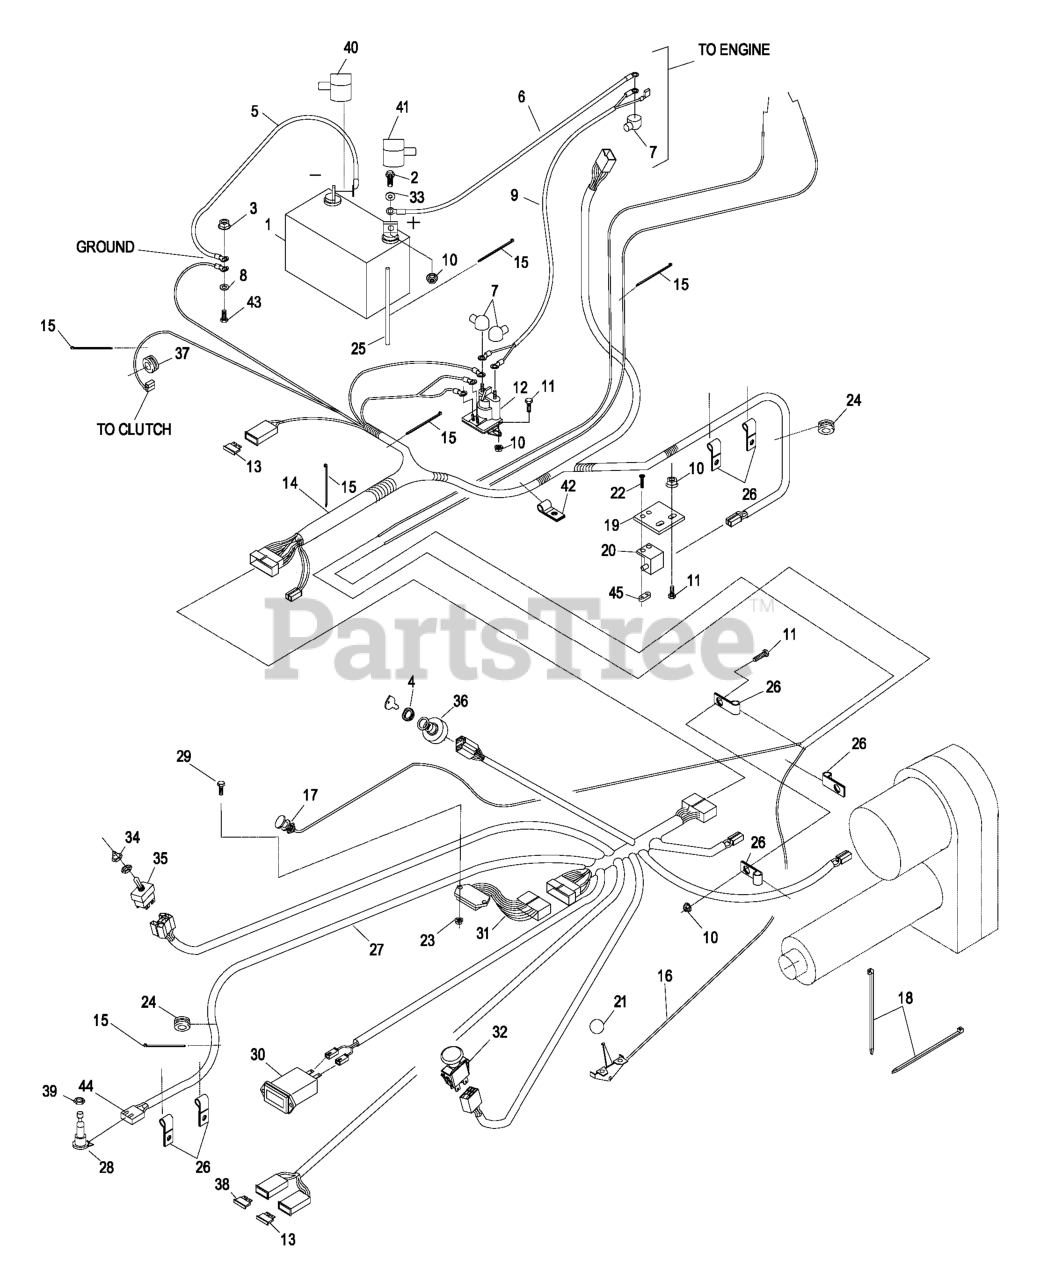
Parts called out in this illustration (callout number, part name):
2	SCREW-HH
4	NUT-SWITCH, IGNITION
5	WIRE-GROUND
7	INSULATOR-SOLENOID
8	WASHER-SPRING
11	SCREW-HH
13	FUSE-BLADE TYPE, 20 AMP
15	TIE-CABLE
16	THROTTLE CABLE ASM
17	CONTROL-CHOKE
18	TIE-PLASTIC
19	BRACKET,SAFETY SWITCH
20	SWITCH-OPEN, NORMALLY
21	KNOB-BALL
22	10-24 X 5/8 FLT HD MS
23	NUT-LOCK, NI
24	GROMMET
26	CLIP-LOOM
27	HARNESS,CONSOLE WIRING
28	SWITCH,PUSH BUTTON
30	METER-HOUR
31	MODULE,OPC
33	WASHER-FLAT
34	BOOT-SWITCH, TOGGLE
35	SWITCH-TOGGLE, DPDT
36	SWITCH,IGNITION
37	GROMMET
38	FUSE-BLADE TYPE, 30 AMP
41	INSULATOR, BATTERY -
42	CLIP-LOOM
43	SCREW-HH
44	CONNECTOR,PACKARD 2 WAY
45	PLATE-TAPPED
